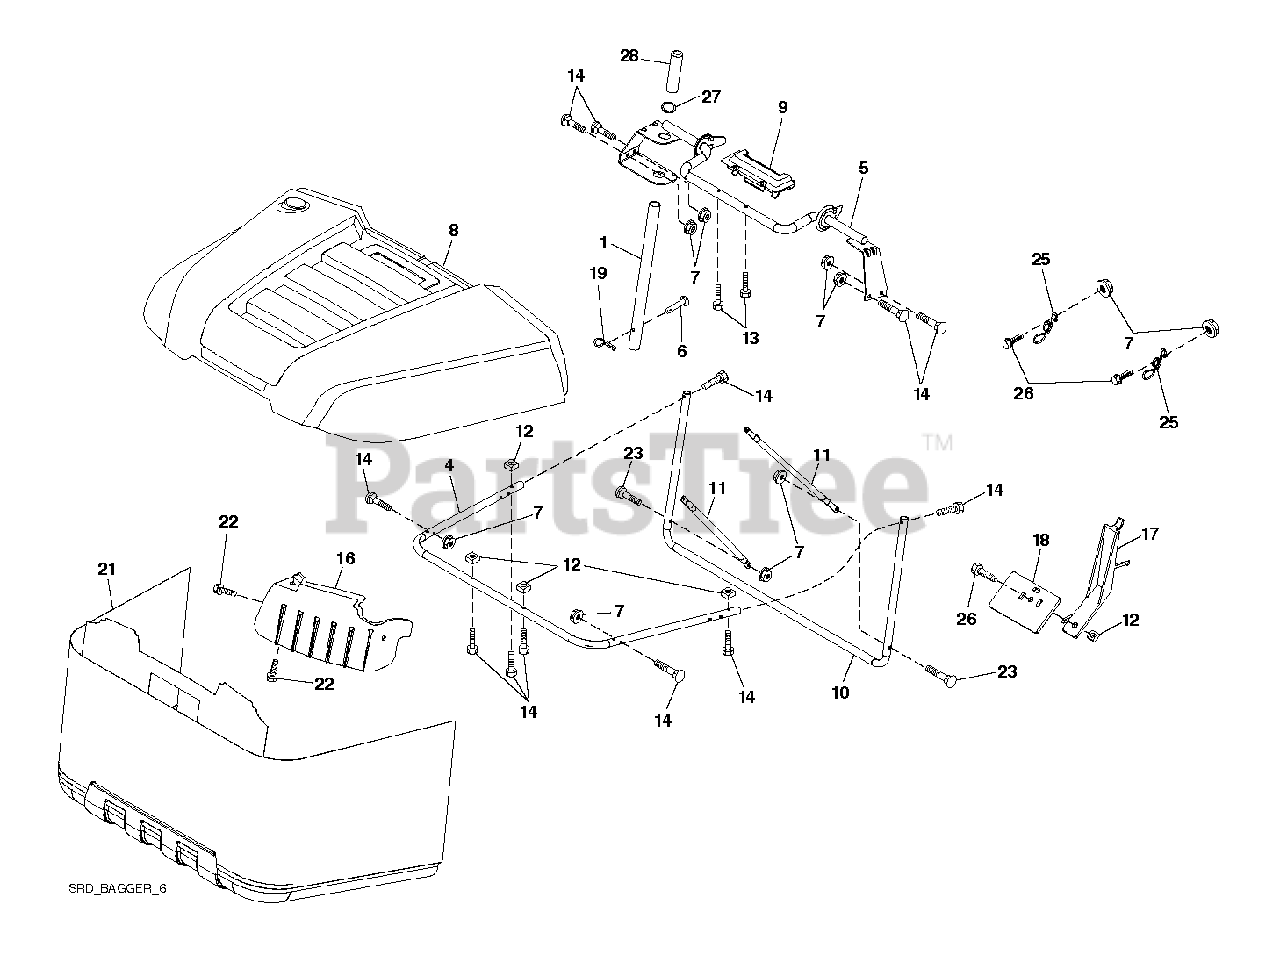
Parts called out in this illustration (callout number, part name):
1	TUBE.HANDLE.BAGGER.CRD/SRD.BLA
4	FRAME.FRONT.SRD.BAGGER
5	FRAME.ASM.TOP.BAGGER.SRD
6	RIVET,DRILLED
7	NUT T
8	BAGGER.TOP.SRD.APPLIQUE
9	INSERT.HANDLE.BAGGER.(2 2)
10	FRAME.FRONT.SRD.BAGGER
11	TUBING.BRACE.BAGGER.SRD.BLACK
12	NUT.SQUARE.1/4
13	SCREW.1/4X1.150.HXWSH
14	BOLT.SHOULDER.HX.WSH.1/4X1.150
16	DEFLECTOR.BAGGER.SRD
17	LEVER.BAGGER.FULL.SRD.BLACK
18	PADDLE.BAGGER.FULL.SRD.BLACK
19	PIN.COTTER.5/16.BOW TI
21	BAG.ASM.BAGGER.SRD.HUSQVA.GREY
22	SCREW.HI-LO.CONSOLE
25	SPRING.LATCH.BAGGER.SRD
26	SCREW HEX CRT
27	RB GROMMET.RUBBER.SRD
28	GRIP.HANDLE.BLACK
